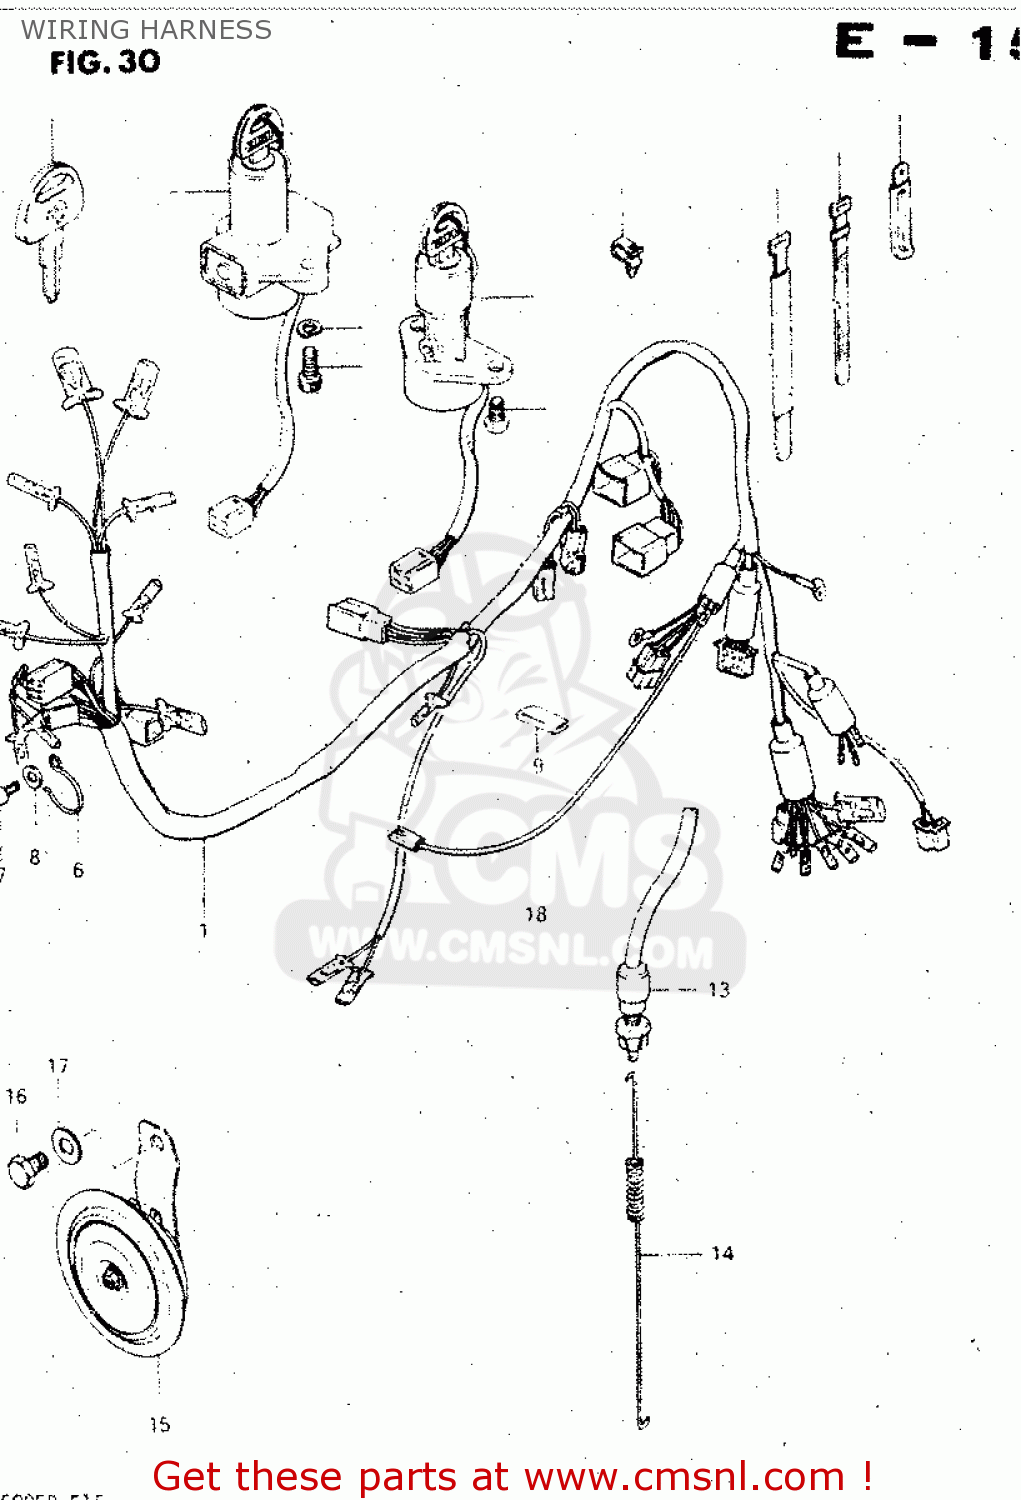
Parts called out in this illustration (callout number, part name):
1	WIRING HARNESS
2	CLAMP
3	CLAMP(L:120)
4	CLAMP
5	CLIP
6	GUIDE,WIRING HARNESS
7	SCREW 6X12
8	WASHER
9	PROTECTOR,WIRING HARNESS
10	LOCK ASSEMBLY,STEERING
11	BOLT
12	LOCK WASHER
13	SWITCH ASSY, IGNITION
14	SCREW
15	SWITCH ASSEMBLY,STOP LAMP
16	SPRING
17	HORN
18	BOLT 8X12
19	WASHER
20	WIRE,OIL PRESSURE SWITCH LEAD
21	KEY,BLANK
